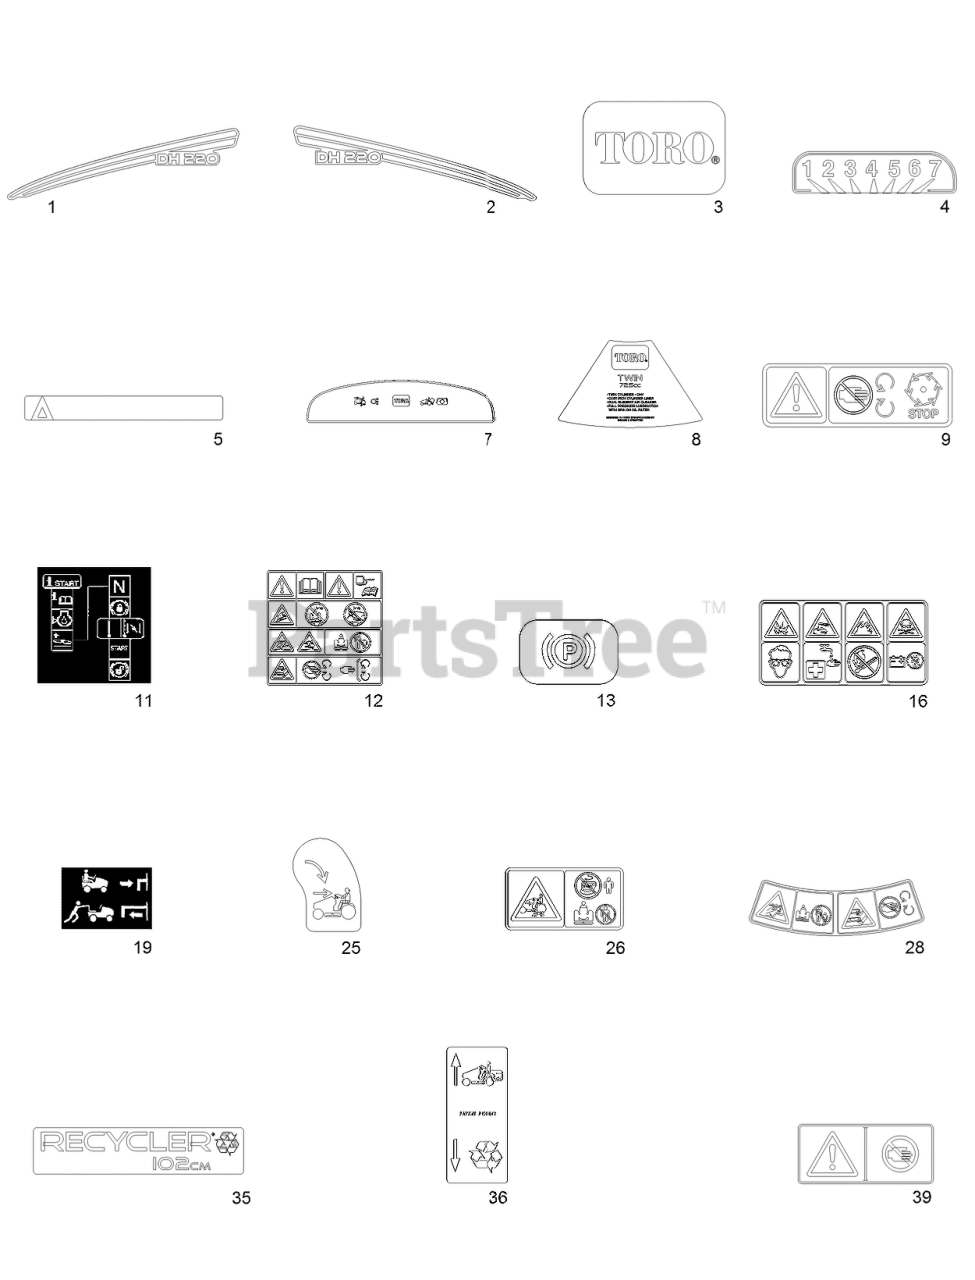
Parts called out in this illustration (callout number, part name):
1	DECAL-HOOD, LEFT
2	DECAL-HOOD, RIGHT
4	DECAL-HOC
5	DECAL-HOC
7	DECAL - DASH, DH 220
8	DECAL-ENGINE
9	DECAL-WARNING, HOOD
11	DECAL-INSTRUCTIONS, OPERATING
12	DECAL-DANGER
13	DECAL-BRAKE, PARKING
16	DECAL-DANGER
19	DECAL-BYPASS
25	DECAL-SWITCH
26	DECAL-DANGER
28	DECAL-DANGER
35	DECAL-RECYCLER
36	DECAL-OPERATION
39	DECAL-WARNING
